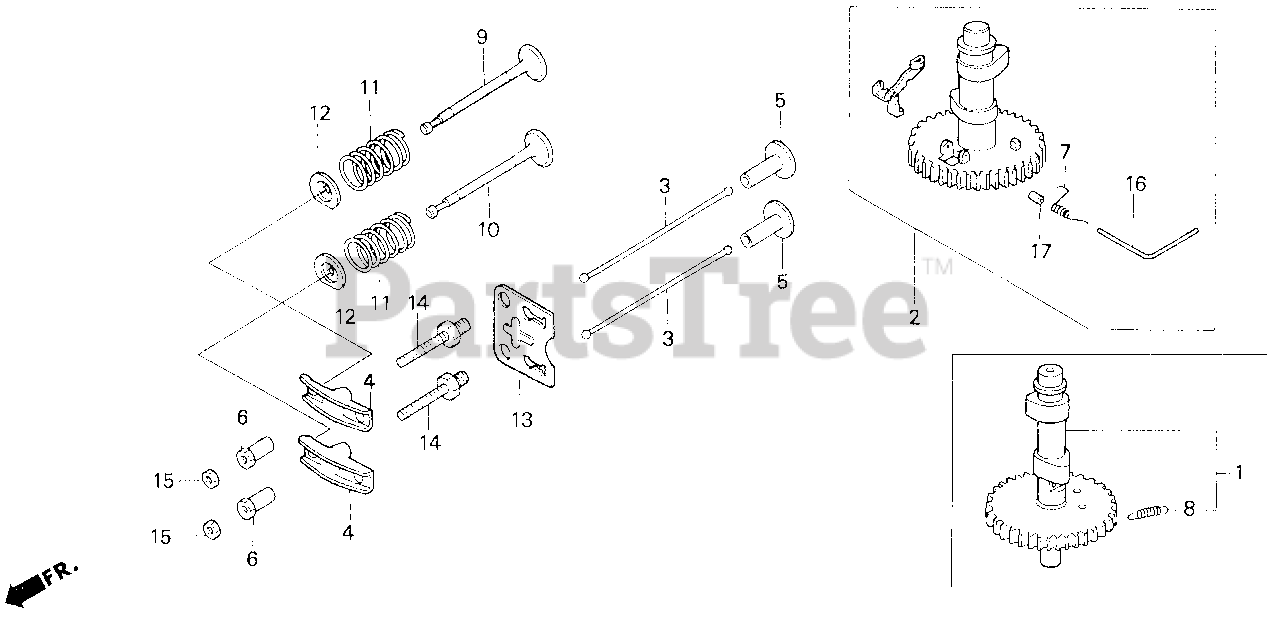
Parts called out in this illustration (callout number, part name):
2	CAMSHAFT ASSY.
3	ROD, PUSH
4	ARM, VALVE ROCKER
5	LIFTER, VALVE
6	PIVOT, ROCKER ARM
8	SPRING, WEIGHT RETURN
9	VALVE, IN.
10	VALVE, EX.
11	SPRING, VALVE
12	RETAINER, VALVE SPRING
12	RETAINER, IN. VALVE SPRING
13	PLATE, PUSH ROD GUIDE
14	BOLT, PIVOT (8MM)
15	NUT, PIVOT ADJ.
16	PIN, WEIGHT CENTER
17	COLLAR, WEIGHT CENTER
